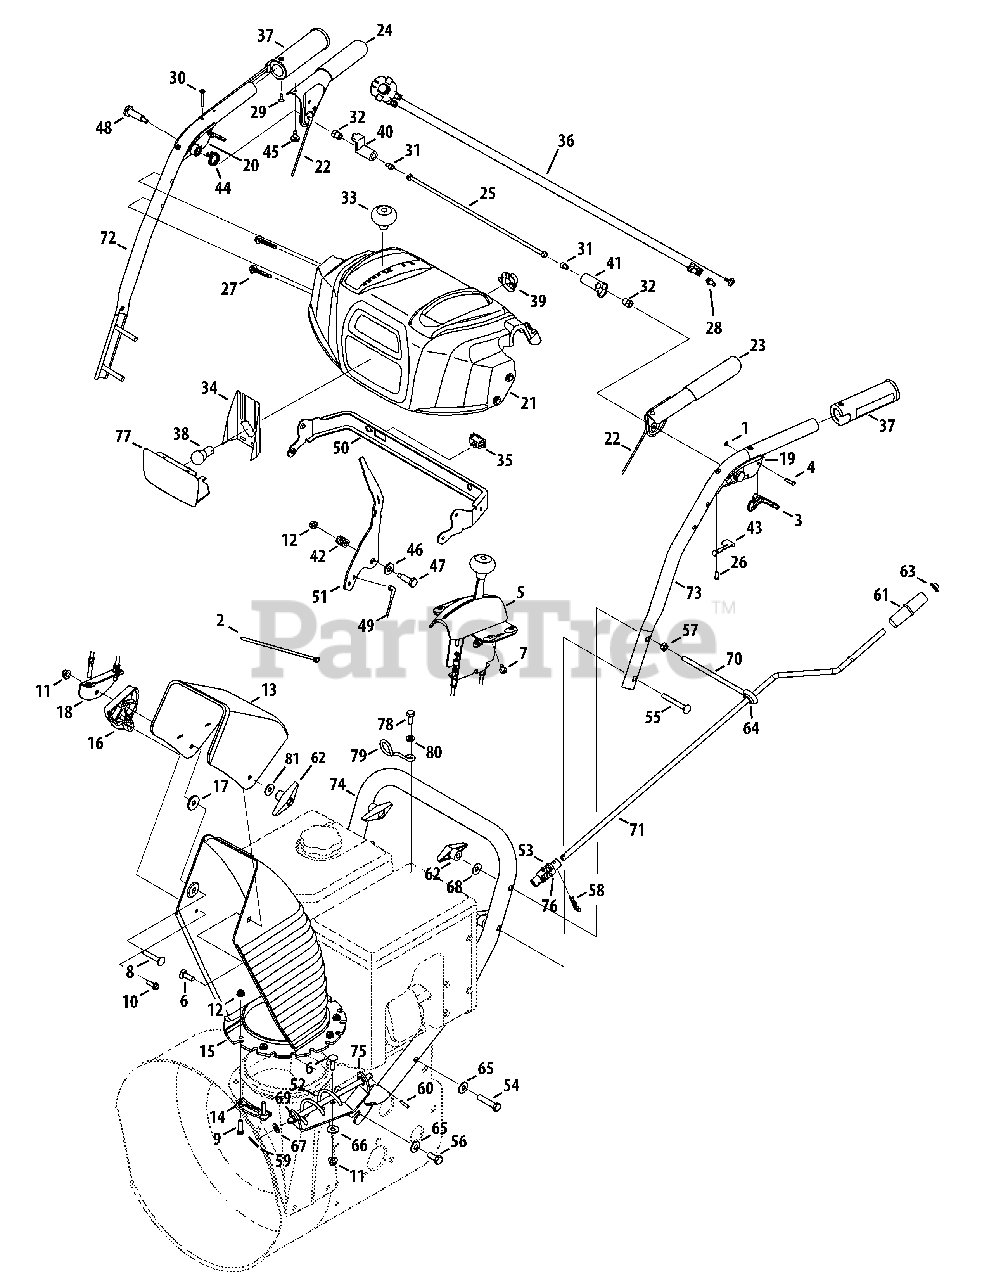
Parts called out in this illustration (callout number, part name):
2	Cable Tie
3	Trigger Lock
5	Chute Control Assembly
6	Carriage Screw, 5/16-18 x 1.0
7	Screw, 1/4-15 x .50
8	Carriage Screw, 5/16-18 x 1.75
9	Hex Screw 1/4-20 x 1.0
10	Screw, 1/4-15 x .750
11	Flange Lock Nut 5/16-18
12	Flange Lock Nut 1/4-20
13	Upper Chute, 6.0
14	Chute Flange Keeper
15	Lower Chute
16	Cbl. Guide, Chute Tilt
17	Flat Wash, .344 x 1.125 x .12
19	Handle Assembly, LH
20	Handle Assembly, RH
21	Handle Panel
22	Cable Ass’y, Auger/Drive
23	Engagement Handle, LH
24	Engagement Handle, RH
25	Clutch Lock Rod Assembly
26	Screw, #8-16 x .50
27	Screw, 1/4-20 x 1.625
28	Hex Screw, 1/4-20 x .5
29	Screw, #10-16 x .625
30	Screw, #10-24 x 1.375
31	Screw, 1/4-20 x .50
32	Nut, Hex, 1/4-20
33	Shift Knob
34	Lens Lable
35	Heated Grip Switch
36	Wire Harness
37	Heated Grip
39	Light Socket
41	Clutch Lock Cam
42	Compression Spring
43	Clutch Lock Spring
44	Torsion Spring, .8156 ID x .3038
45	Rubber Bumper
46	Flat Washer, .385 x .87 x .06
47	Screw, Shldr., .374 x 1.05
48	Screw, Shldr., .437 x 1.345
49	Clutch Cable
52	Chute Crank Assembly
53	Joint Block Assembly
54	Hex Screw, 3/8-16 x 2.00
55	Carriage Screw, 5/16-18 x 2.5
56	Screw, Hex, 3/8-16 x 1.00
57	Nut, Hex, 5/16-18
58	Internal Cotter Pin
59	Internal Cotter Pin
60	Spring Pin, .156 dia. x .875 Lg.
61	Knob, Crank
62	Knob, Wing Nut, 5/16-18
63	Push Cap, 3/8
64	Rubber Grommet
65	Bell Wash, .375 x .87 x .063
66	Flat Washer, .349 x .879 x .063
67	Flat Wash, .375 x .738 x .063
68	Wash, Bell, .34 x .872 x .06
69	Plastic Bushing, .38 ID
70	Eye Bolt, .70 Dia.
71	Chute Rod, .375 Dia. x 29.72
76	Roll Pin, 3/16 Dia. x 1.100
78	Hex Screw, M8-1.25
79	Cable Guide
80	Flat Washer, .330 x .630 x .0635
81	Washer, Flat, .349 x .879
